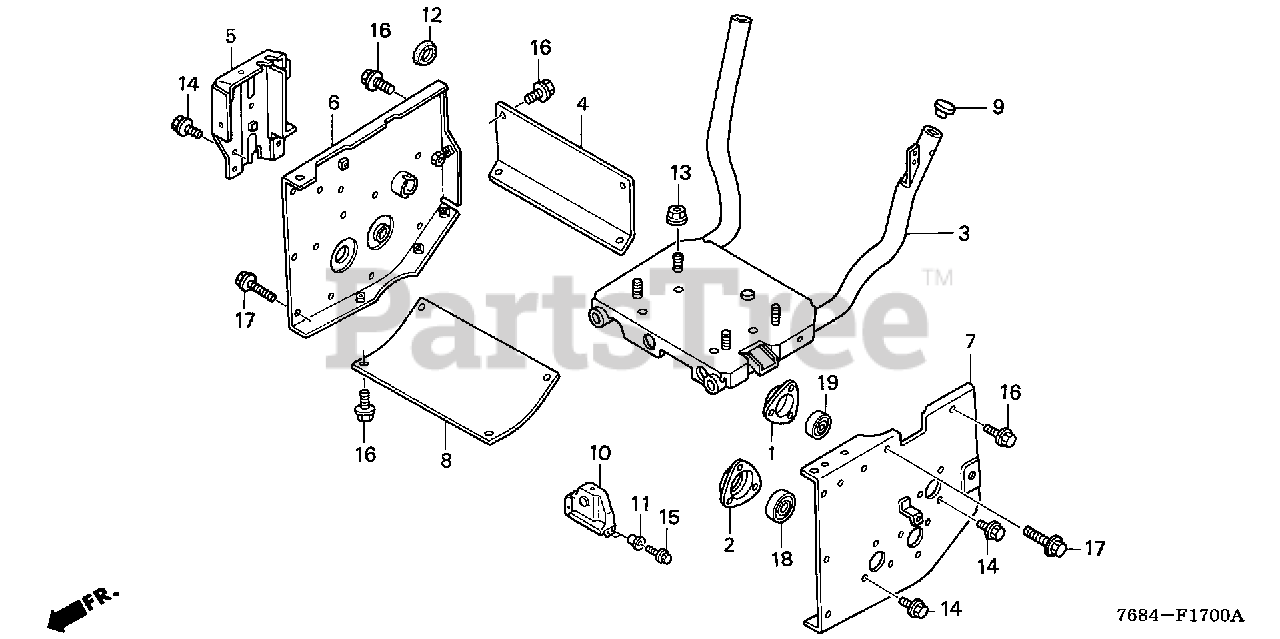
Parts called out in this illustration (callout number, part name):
1	HOLDER, BEARING
2	HOLDER, WHEEL SHAFT BEARING
3	BED, ENGINE
4	STAY, ENGINE BED
5	HOLDER, WIRE
6	STAY, R. ENGINE BED
7	STAY, L. ENGINE BED
8	STAY, ENGINE BED (B)
9	CAP, HANDLE (LOWER)
10	COVER, BELT
11	WASHER, CHAIN CASE SETTING
12	COVER, DUST (28MM)
13	NUT, FLANGE (10MM)
14	BOLT, FLANGE (6X12)
15	BOLT, FLANGE (6X14)
16	BOLT, FLANGE (8X12)
17	BOLT, FLANGE (8X16)
18	BEARING, RADIAL BALL (6004UU)
19	BEARING, RADIAL BALL (6201UU)
